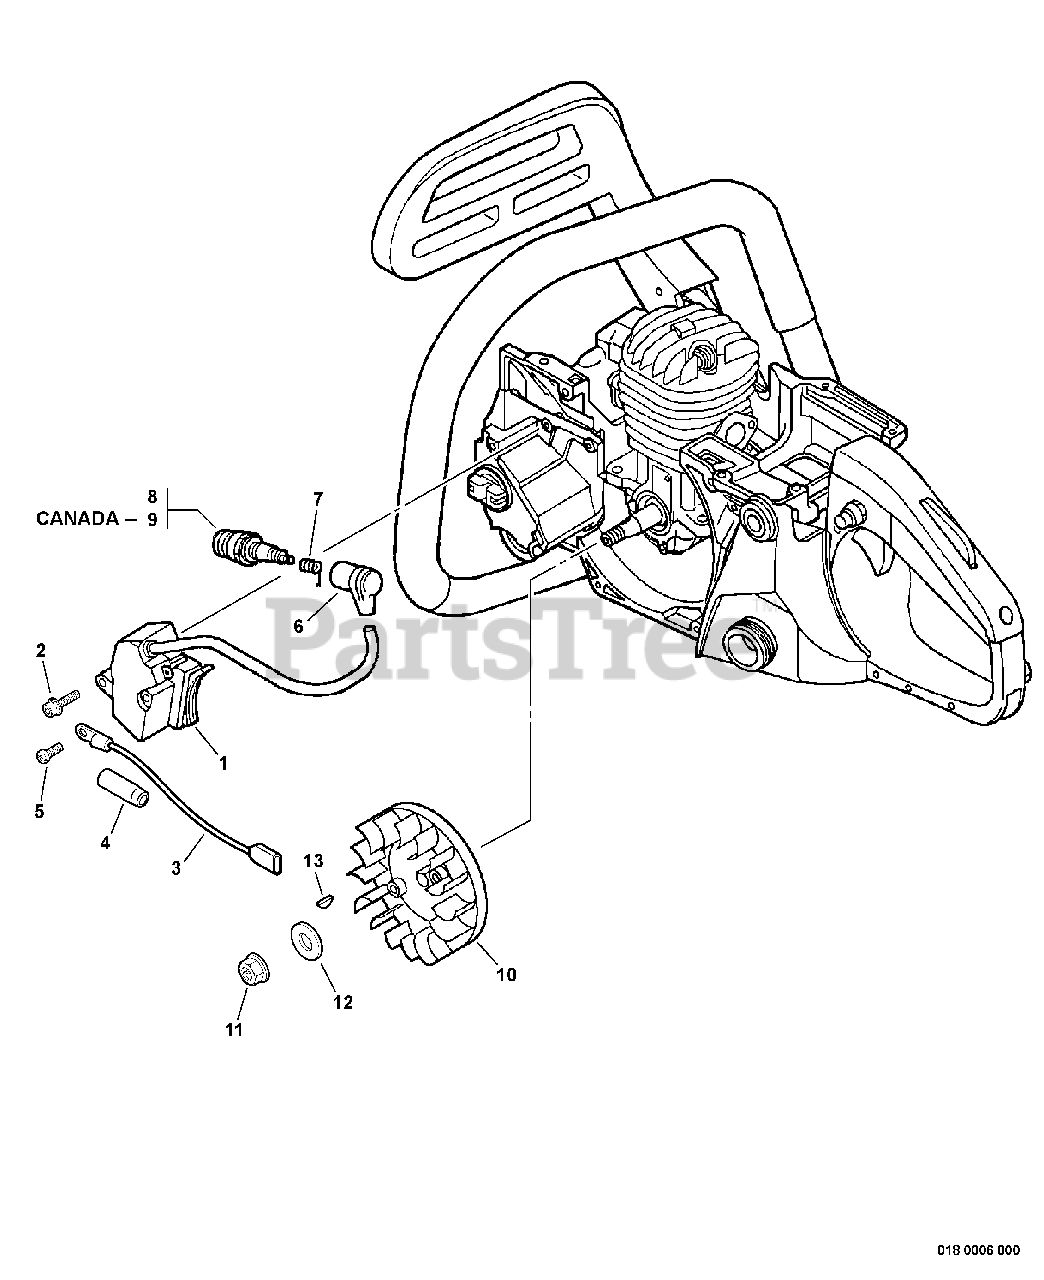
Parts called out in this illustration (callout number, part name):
1	COIL, IGNITION
2	SCREW - 4X30
3	LEAD - GROUND
4	BOOT, CONNECTOR
5	SCREW - 4X6
6	CAP, SPARK PLUG
7	TERMINAL, SPARK PLUG CAP
8	SPARK PLUG -- BPM-8Y
9	SPARK PLUG -- BPMR-8Y
10	FLYWHEEL
12	LOCKWASHER - 8
